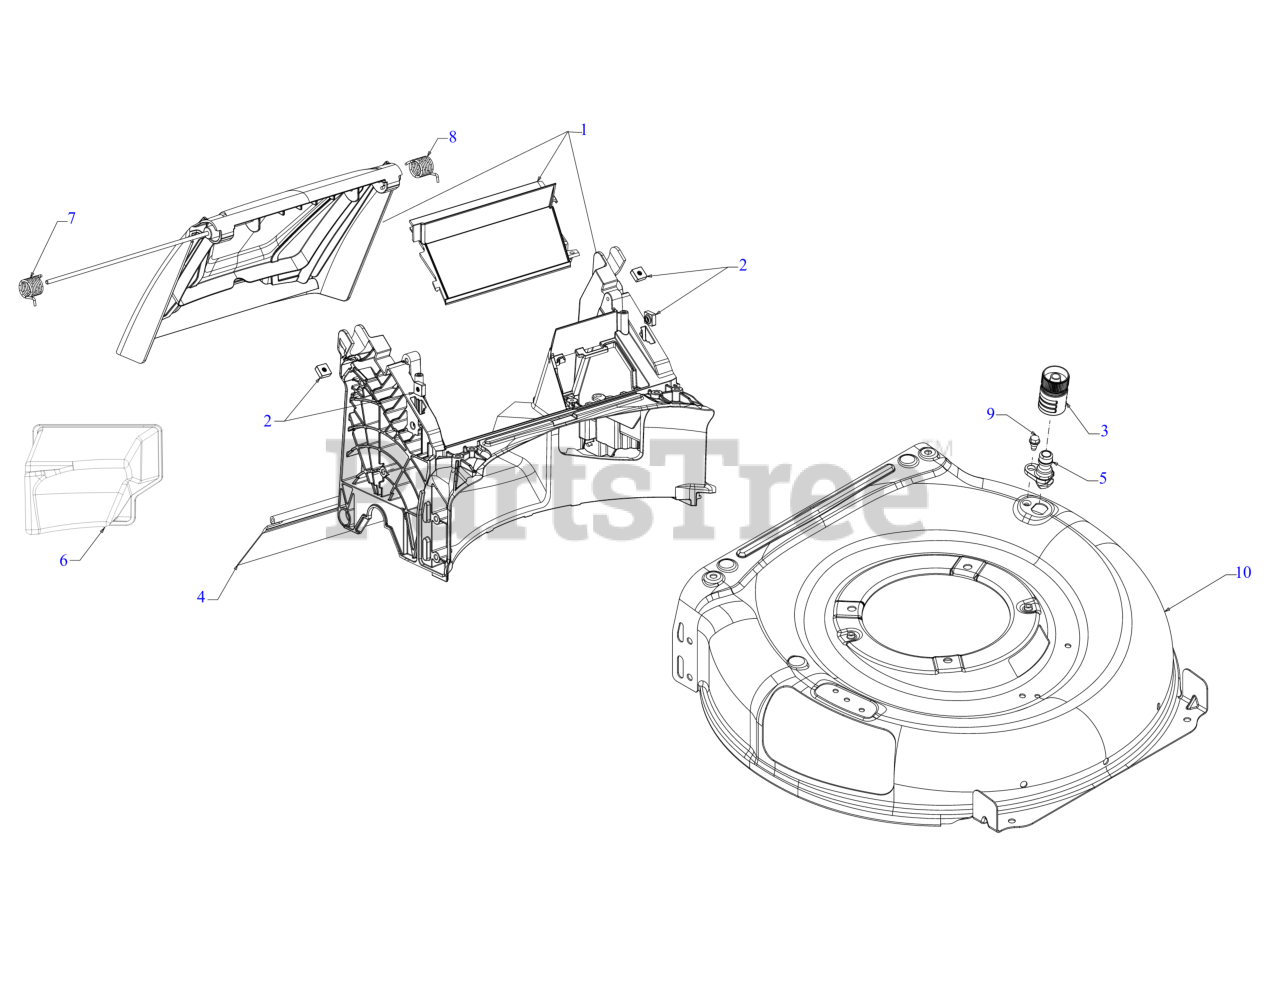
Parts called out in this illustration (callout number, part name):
1	21" BAFFLE ASSEMBLY (REAR)
2	SQUARE LOCK NUT 1/4X20
3	WATER NOZZLE ADAPTER
4	TRAILSHIELD
5	DECK WASH NOZZLE
6	21" MULCH PLUG
7	TORSION SPRING (RH)
8	TORSION SPRING (LH)
9	SHOULDER SCREW 1/4-20 x .50
